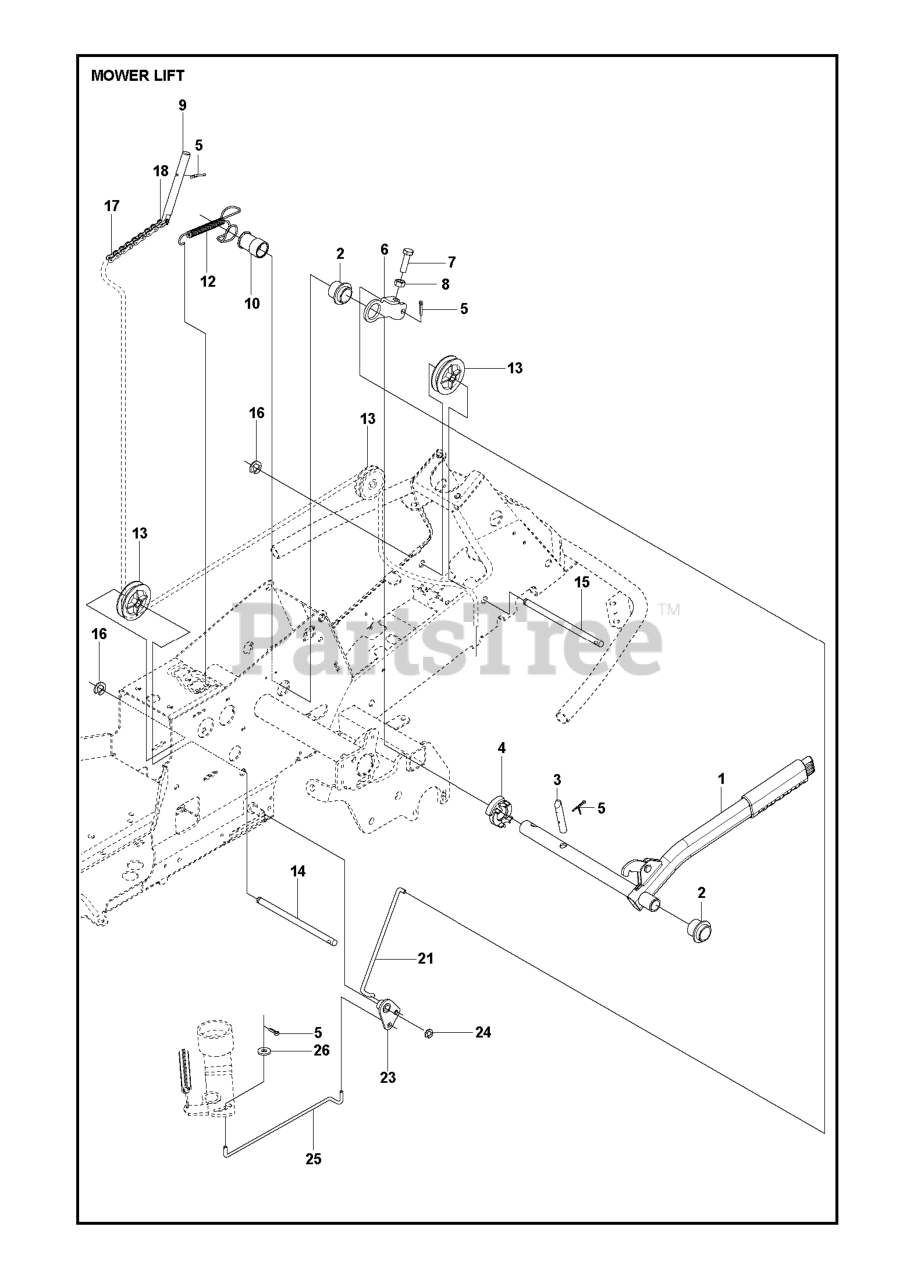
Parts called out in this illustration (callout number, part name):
2	BEARING FLANGE
6	LIFTING ARM LINK
21	CONNECTION ROD
24	RETAINING RING
25	CONNECTION ROD
